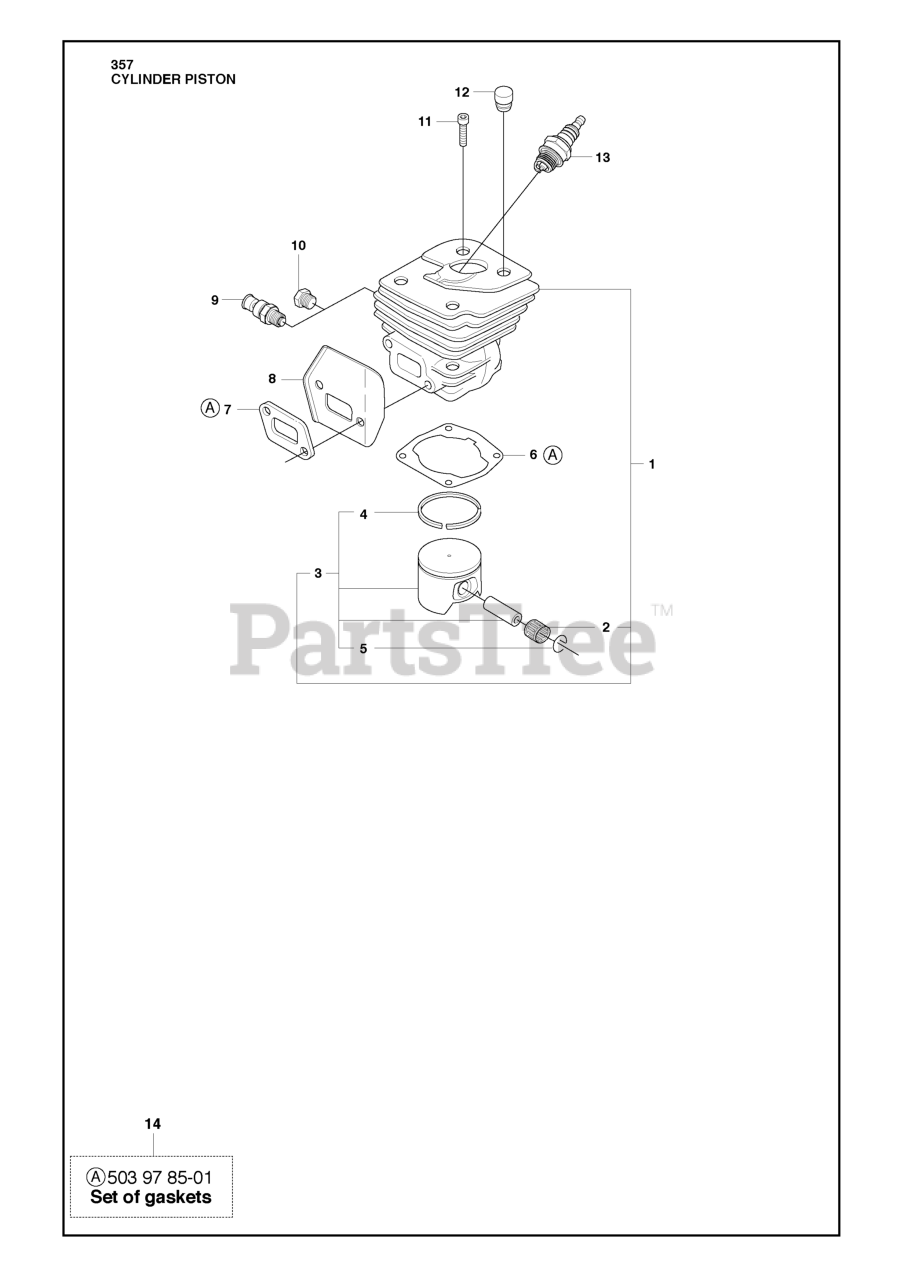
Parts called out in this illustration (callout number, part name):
2	SUPPORT BUSHING
3	PISTON ASSY
4	PISTON RING
5	WRIST PIN CLIP
8	HEAT DEFLECTOR
9	DECOMPRESSION VALVE
10	CYLINDER PLUG
11	SCREW MC6S 5X25
13	SPARK PLUG RCJ7Y
14	GASKET SET
